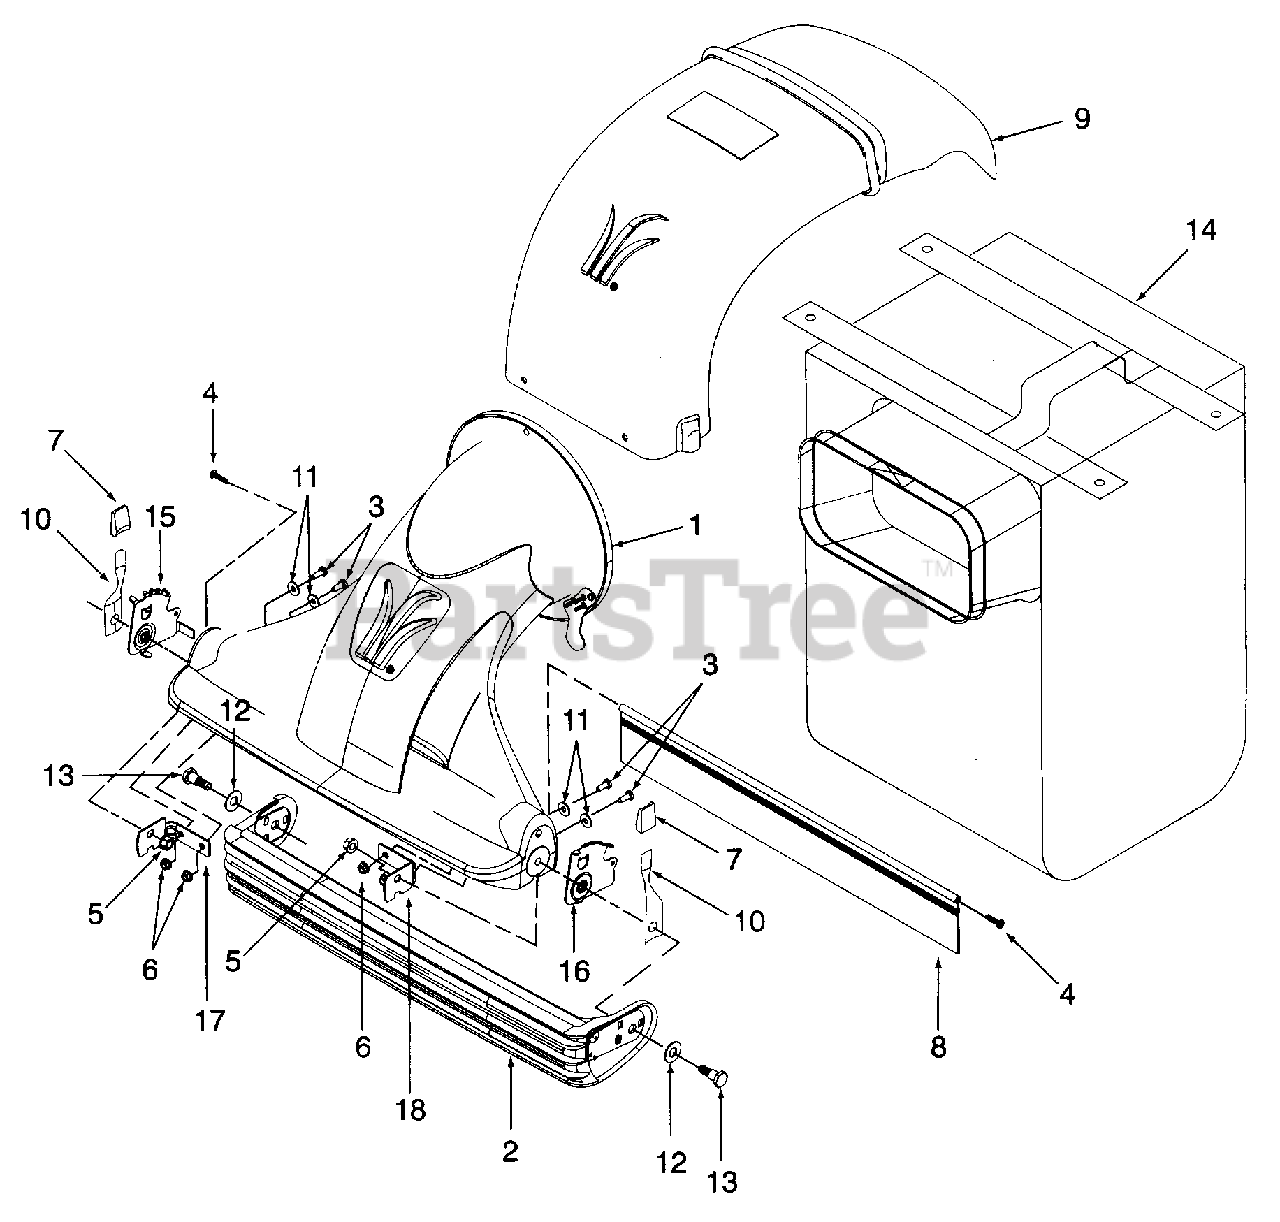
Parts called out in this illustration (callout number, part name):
1	Nozzle Assembly, Black
2	Door Assembly, Black
3	Screw, Hex Cap, 1/4-20 x .625
4	Screw, Truss Hd Tapp
5	Nut, Hex Flange Lock, 3/8-16
6	Nut, Hex Flange Lock, 1/4-20
7	Knob, Height Adj
8	Flap, Nozzle Rear
9	Discharge Chute
10	Spring Lever
11	Washer, Flat, .28 x .74 x .06
12	Washer, Flat, .510 x 1.20 x .060
13	Screw, Shoulder, .50 x .545 x 3/8-16
14	Bag, 3 Bushel
17	Racket, Nozzle Reinforcement RH
18	Bracket, Nozzle Reinforcement LH
